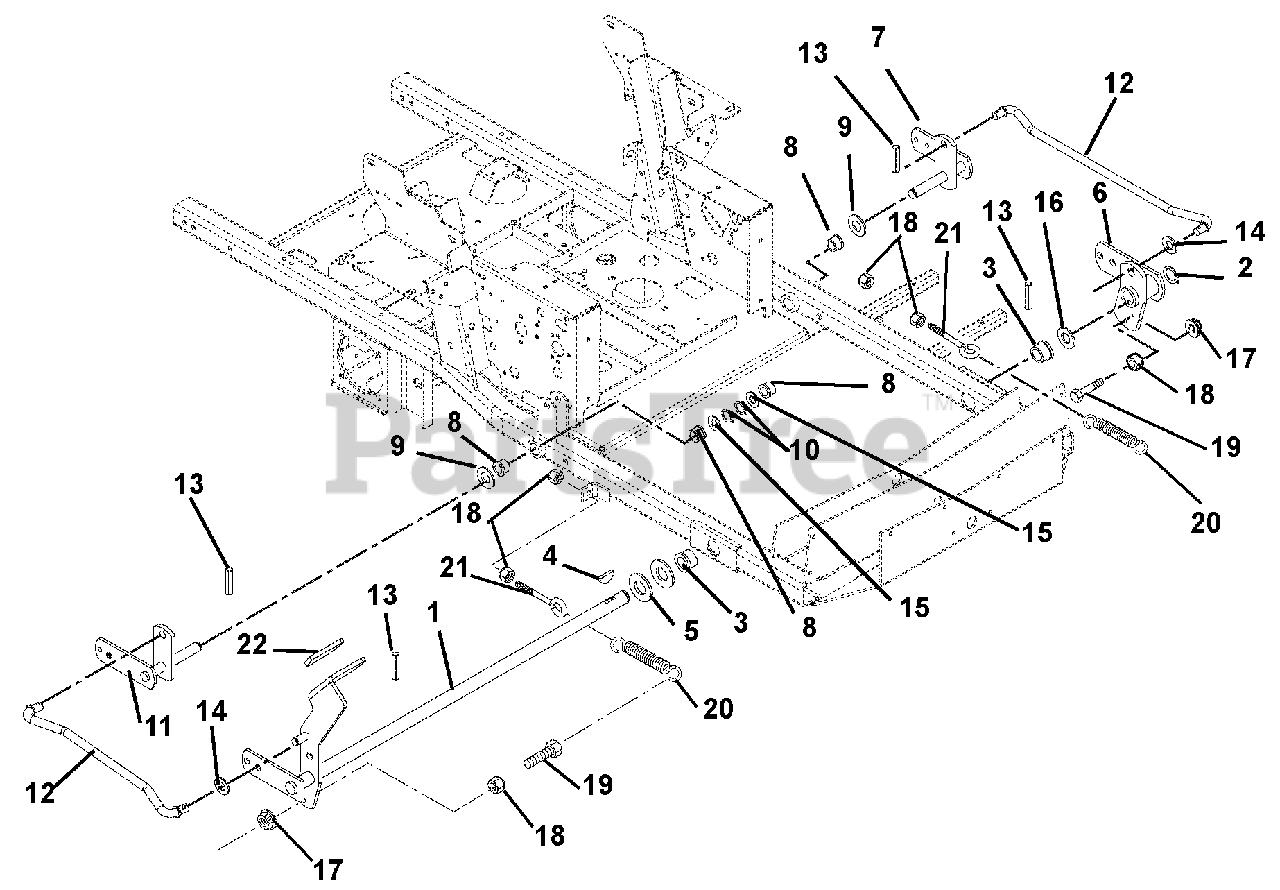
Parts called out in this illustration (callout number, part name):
1	Lift Mower (045, 046, 047, 052, 066, 067, 068, 071, 084, 085, 086, 091, 104, 106, 107, 108)
2	Ring, Retaining External 1.00 x .078
3	Bushing, Flange Nylon 1.020 x 1.385 x .75 x 1.75
4	Key, Woodruff .25 x 1.00
5	Washer, Flat Steel 1.062 x 2.00 x .134
6	Weldment, Lift Arm Front
7	Weldment, Lift Arm Shaft Left Hand
8	Bushing, Flange Nylon .762 x 1.00 x .58 x 1.48
9	Washer, Hardened Steel .758 x 1.23 x .031
10	Ring, Retaining External .689 x .077
11	Weldment, Lift Arm Shaft Right Hand
12	Rod, Lift Assist
13	Pin-Roll .250 x 1.25 Stainless Steel
14	Washer-Flat-Steel .630 x 1.25 x .062
15	Washer, Flat Steel .755 x 1.25 x .125
16	Washer, Hardened Thrust 1.00 x 1.55 x .03
17	Nut, Locking-Top-Flange .38-16 (087, 088, 089, 102, 103, 105)
18	Nut, Hex .38-16 (087, 088, 089, 102, 103, 105)
19	Bolt, Hex .38-16 x 1.75 Grade 5 (087, 088, 089, 102, 103, 105)
20	Spring, Tension .162 x 1.25 x 8.25 (087, 088, 089, 102, 103, 105)
21	Bolt, Eye .375-16 x 2.50 (087, 088, 089, 102, 103, 105)
22	Grip, Foot Pedal
